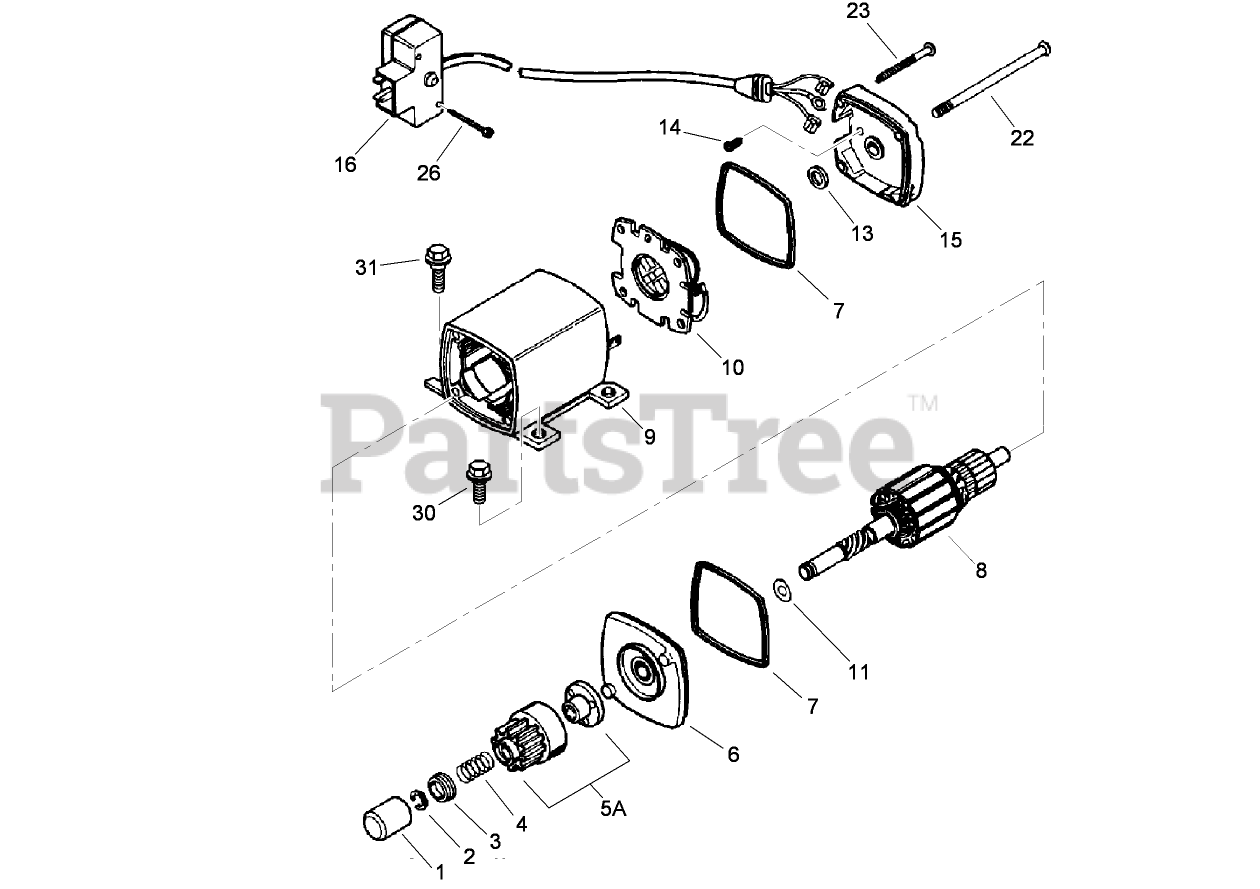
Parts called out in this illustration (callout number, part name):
1	Cover-Dust
2	Ring-Retainer
3	Retainer-Spring
4	Spring-Anti Drift
5A	Gear Nut (Incl. Ref.# 2)
6	Cap Assembly-Cap End (Incl. Ref. #7)
7	O-Ring
8	Armature
9	Housing ASM
10	Brush Card ASM
11	Washer-Thrust
13	Washer-Thrust
14	Screw-Ground
15	Cap Assembly (Incl. Ref. #7)
16	Box Assembly-Switch (Incl. Ref. #26)
22	Bolt-Case
23	Screw-Ground
26	Screw
26	Screw (12-16 x 5/8)
30	Screw
31	Screw (1/4-20x1/2)
